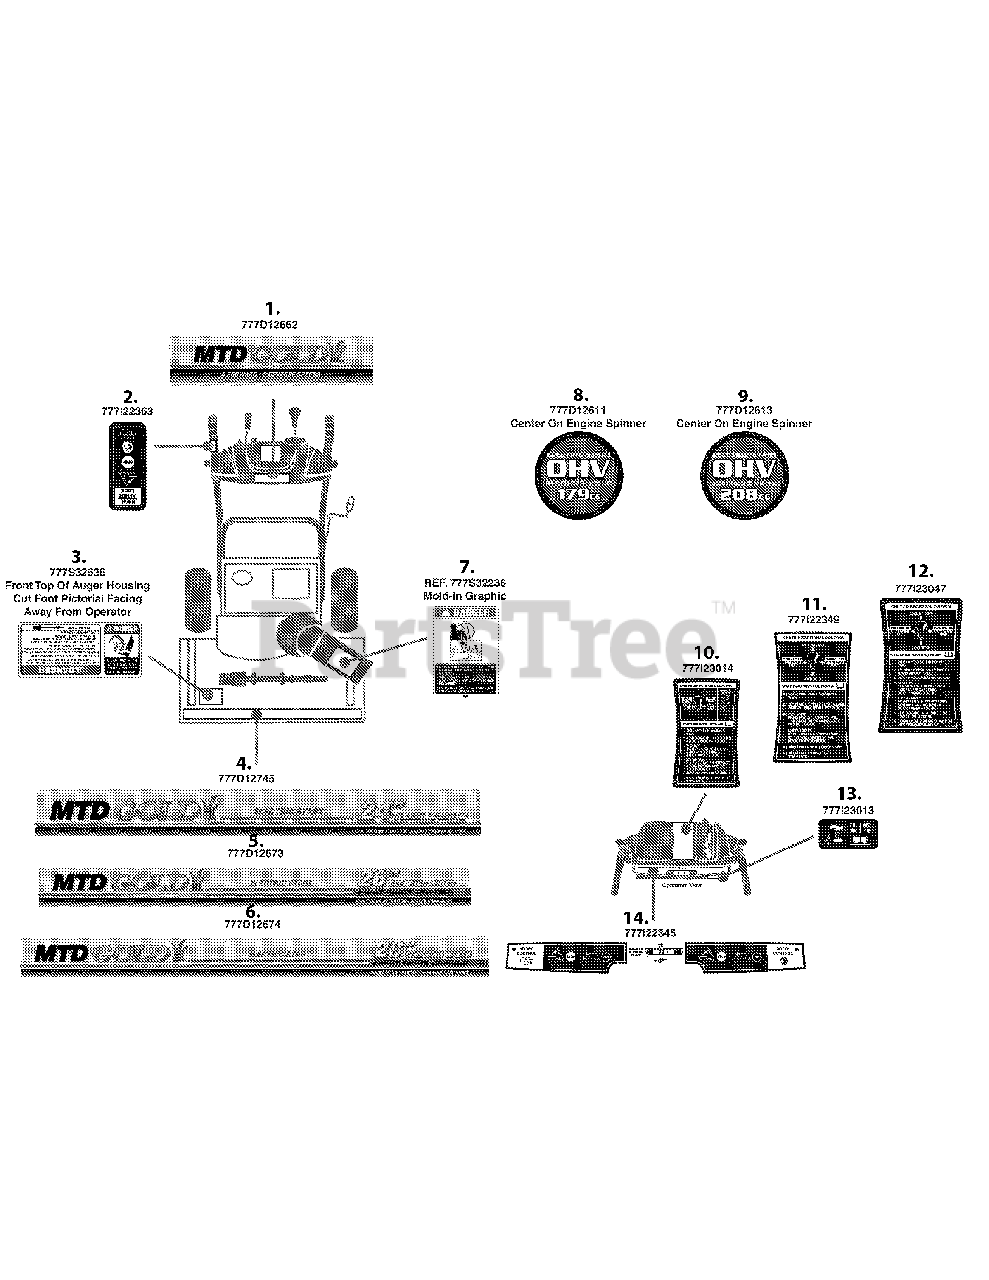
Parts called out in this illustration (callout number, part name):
1	LABEL:SNW:L PNL:MTD GOLD
2	LABEL:DRV/AUGR LOCK
3	LABEL:SNOW HOUSING
4	LABEL:SNW:HSG:MTD GOLD 24"
5	LABEL:SNW:HSG:MTD GOLD 26"
6	LABEL:SNW:HSG:MTD GOLD 28"
7	LABEL:SNOW CHUTE
8	LABEL:ENG/SPN:OHV/ES/179
9	LABEL:ENG/SPN:OHV/ES/208
10	LABEL:SNW:K PNL:2-WAY/MNL PTCH
11	LABEL:SNOW:HANDLE PA
12	LABEL:SNW:L PNL:ST INSTR:B&S
13	LABEL-SNOW 2 STAGE HTD HANDLES
